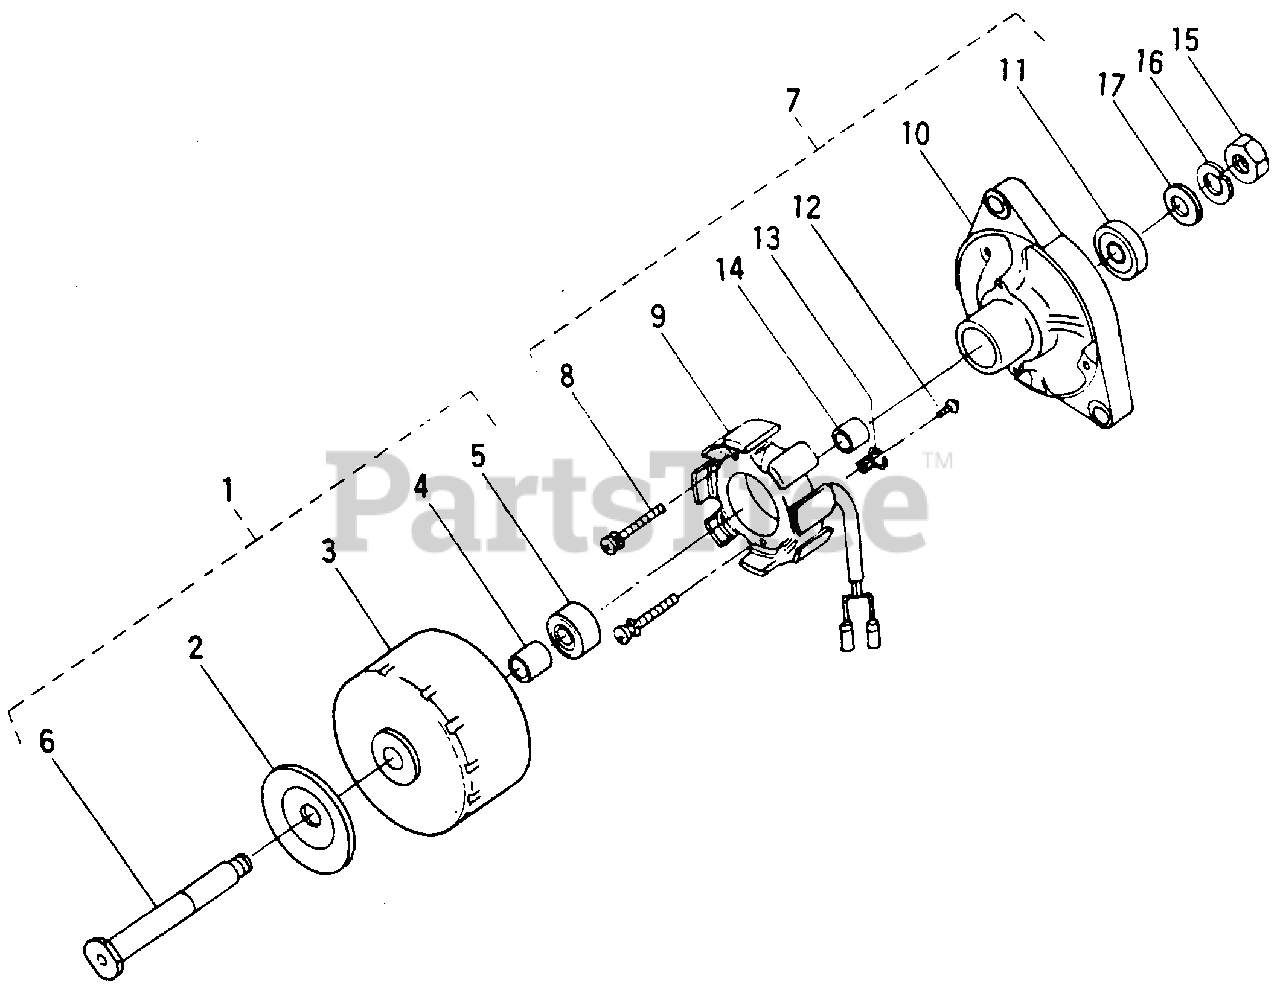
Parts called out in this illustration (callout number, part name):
1	Rotor Assy
5	Bearing, Ball
7	Stator Assy
8	Screw, Round Head
11	Bearing, Ball
12	Screw, Round Head
16	Washer, Spring
17	Washer, Plain
